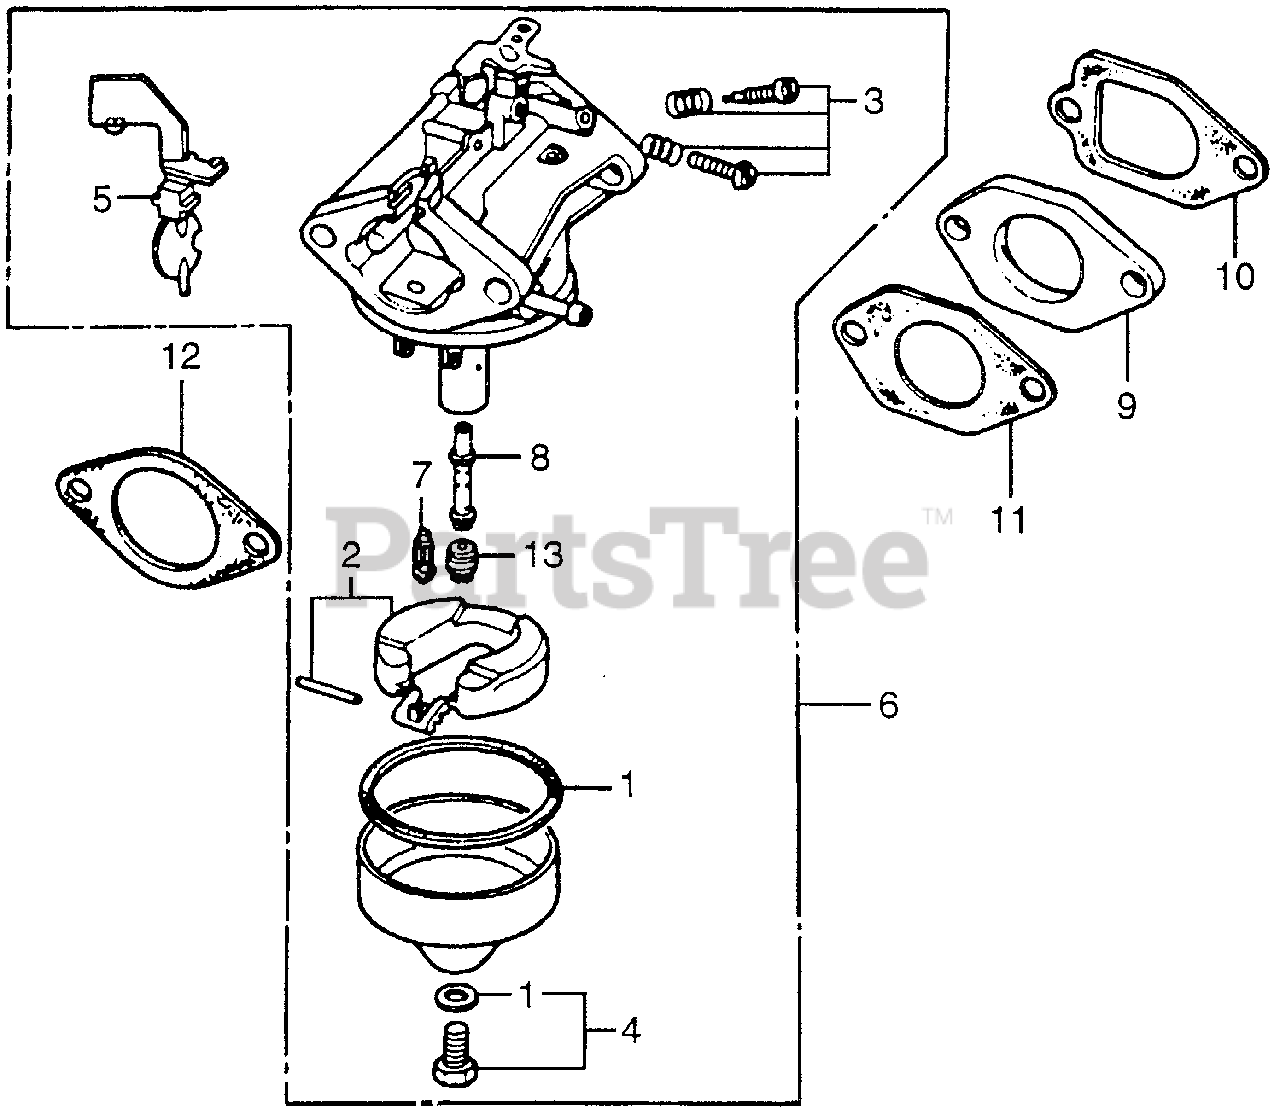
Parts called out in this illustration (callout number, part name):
1	GASKET SET
3	SCREW SET A
4	SCREW SET B
6	CARBURETOR ASSY.
7	VALVE, FLOAT
8	NOZZLE, MAIN
9	INSULATOR, CARBURETOR
10	GASKET, INSULATOR
11	GASKET, CARBURETOR
12	GASKET, AIR CLEANER
13	JET, MAIN (#65)
13	JET, MAIN (#68)
13	JET, MAIN (#70)
13	JET, MAIN (#72)
